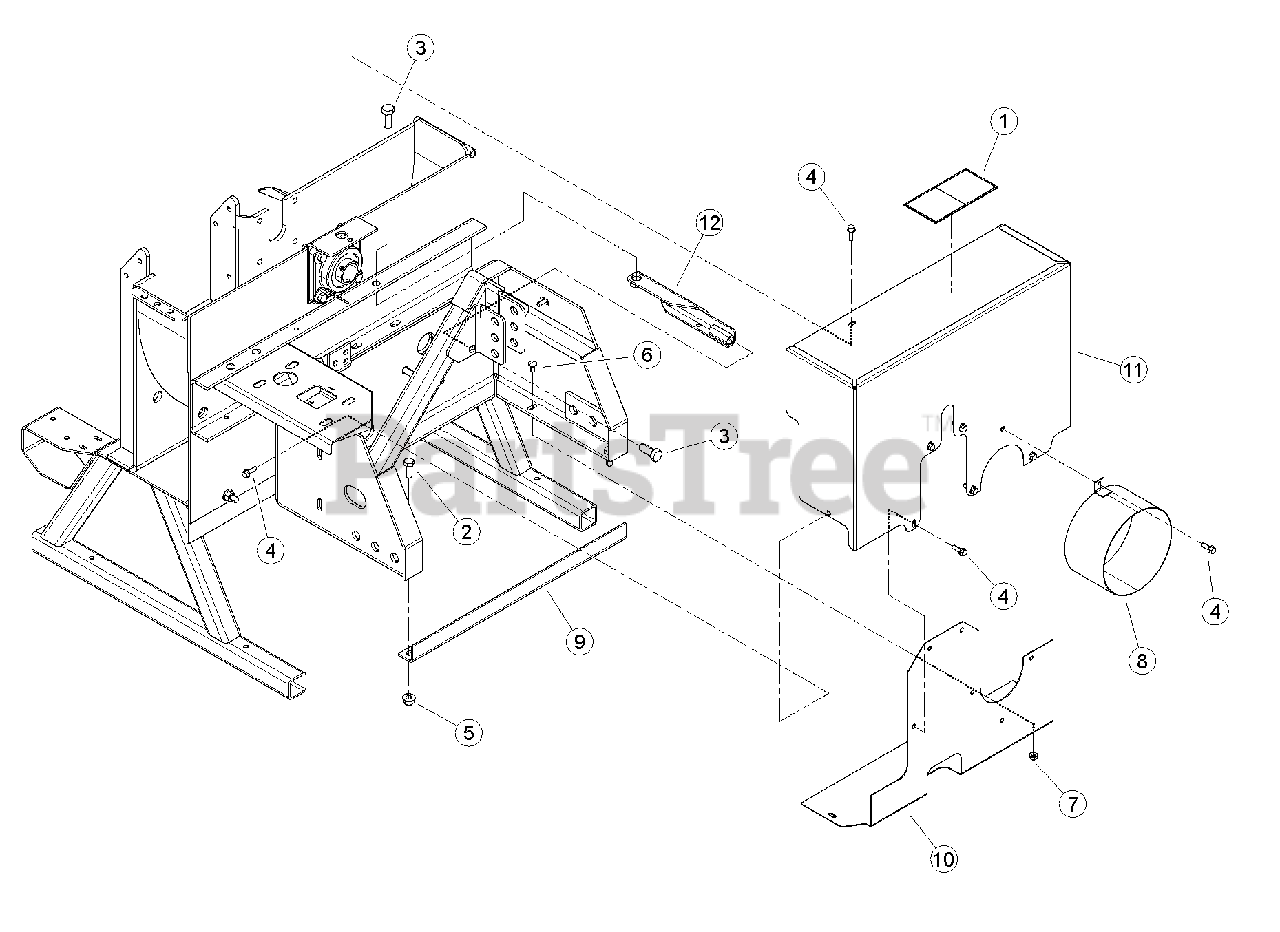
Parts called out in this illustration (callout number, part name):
1	DECAL, PTO DANGER ISO
2	BOLT, 1/2 X 1-1/4" GR5 HHCS NC ZP
3	BOLT, 5/8 X 1-1/2 HEX HD GR5 ZP
4	BOLT, 5/16 X 1 FLANGE NC
5	NUT, 1/2-13 NYLOCK FLANGE
6	BOLT, 5/16-18 X 1 GR5 CRG
7	NUT, 5/16-18 NYLOCK FLANGE
8	WELDMENT, PTO SHIELD
9	BRACE, 3 PT BOTTOM
10	WELDMENT, GUARD PTO LOWER BELT
11	WELDMENT, GUARD PTO UPPER BELT
12	WELDMENT, BRACE PTO 3-POINT
